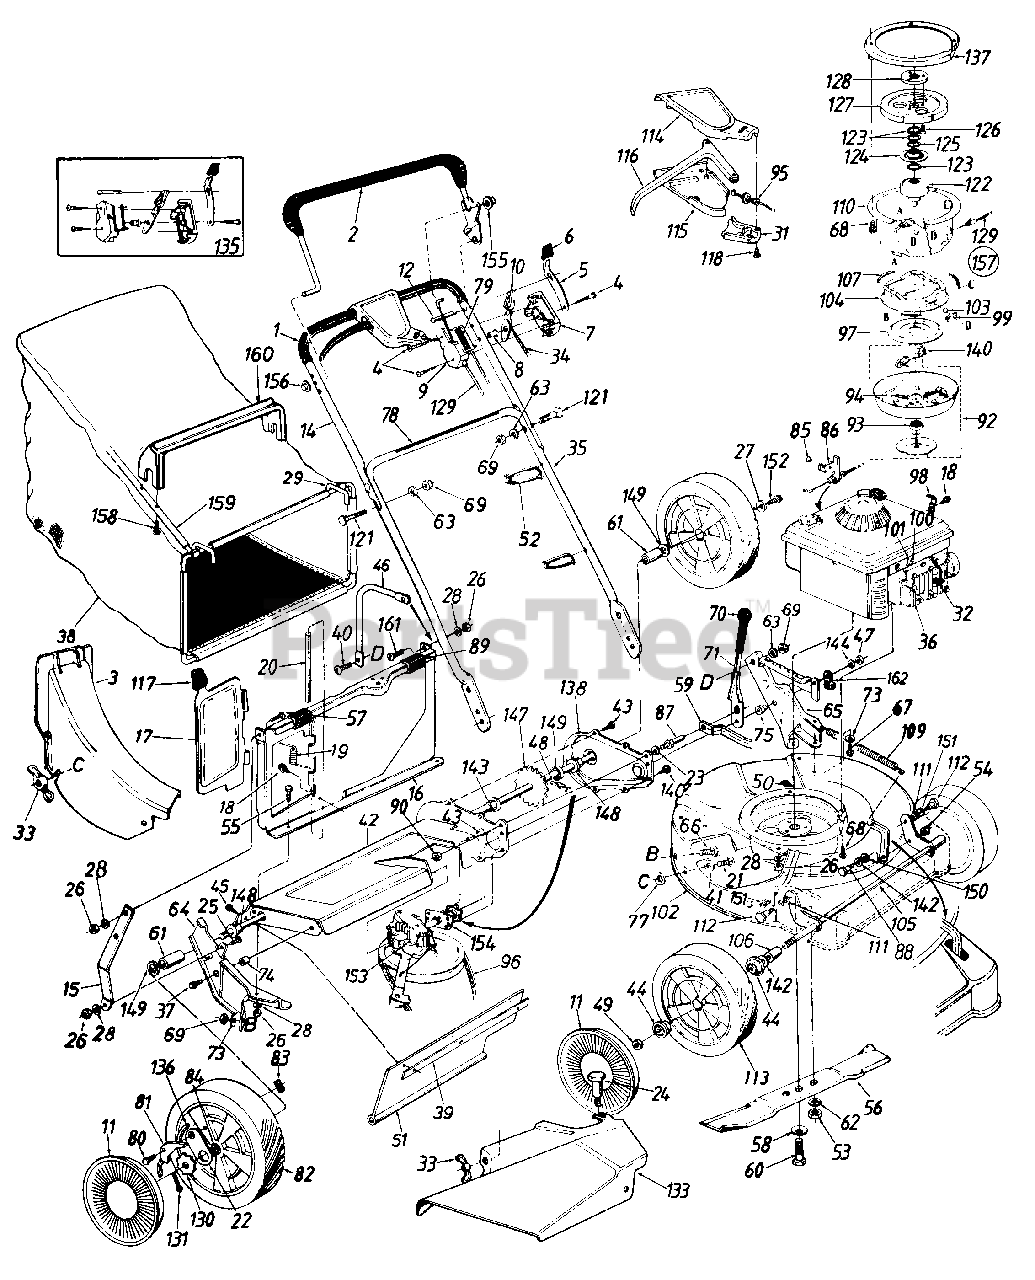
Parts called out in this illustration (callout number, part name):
1	Grip
2	Control Handle Ass'y.-L.H.
3	Rear Discharge Chute Ass'y.
4	Truss Mach. Scr. #12 x 1.50" Lg.
5	Lockout Spring
6	Spring Lever Knob
7	Control Panel Half
8	Control Disc Pin
9	Clutch Panel Half
10	Throttle Control Lever
11	Hub Cap (Radial)
12	Lock Pin .314" Dia. x 1.75"
14	Upper Handle
18	Hex B-Tap Scr. #10 x .38"
19	Torsion Spring
20	Pivot Pin
21	Carriage Bolt 1/4-20 x .62"
22	Pawl Plate
23	L-Wash. 3/8" I.D.*
24	Shoulder Bolt .312" Dia. x .18" Lg. Special
25	Hex Bolt 1/4-20 x .62" Lg.
26	Hex Nut 1/4-20 Thd.
27	Bell-Wash. 1/4" I.D.
28	L-Wash. 1/4" I.D.
31	S.P. Control Cover
32	Spark Plug Insulator
33	Wing Nut
34	Throttle Control Wire 58" Lg.
35	Lower Handle
36	Engine
37	Hex L-Wash. TT-Tap Scr. 3/8-16 x 1" Lg.
38	Grass Bag-Grey
39	Retaining Strip
40	Truss Mach. Scr. 5/16-18 x .75" Lg.
41	Fl-Wash. .344" I.D. x .62"
44	Flange Ball Bearing 1/2" I.D.
45	Hex AB-Tap Scr. 1/4 x .62"
46	Catcher Panel Support Arm
47	Hex Patch L-Nut 3/8-24 Thd.
48	#48 Chain .500" Pitch x 30 Links
49	Hex L-Nut 1/2-20 Thd.
51	Rear Flap 3.75" x 17.30" Lg.
52	Cable Tie
53	Hex Nut 3/8-24 Thd. (Grade 8)
54	Hex Jam Nut 3/8-16 Thd.
55	Hex Bolt 1/4-20 x .5" Lg.
56	21" Blade
57	Truss Mach. Scr. 1/4-20 x .75" Lg.
58	Bell-Wash. .46" I.D. x .88" O.D.
59	Height Adj. Connecting Arm
60	Hex Bolt 7/16-20 x 2.0" Lg. (Grade 5)
61	Spacer .513" I.D. x .703" O.D. x .69" Lg.
62	L-Wash. 3/8" I.D.
63	L-Wash. 5/16" I.D.
64	R.H. Handle Wheel Brkt. Ass'y.
65	L.H. Handle Wheel Brkt. Ass'y.
66	Carriage Bolt 5/16-18 x .62"
67	Hex Wash. Hd. B-Tap Scr. 5/16-18 x .5" Lg.
68	Hex Wash. Hd. TT-Tap Scr. 3/8-16 x 1.5" Lg.
69	Hex Nut 5/16-18 Thd.
71	Height Adj. Lever
73	Bell-Wash. 5/16" I.D.
74	Spacer .383" I.D. x .503" O.D.
75	Shld. Spacer .500" Dia. x . 1 00"
77	Bolt Retainer 1/4 x .50" O.D.
78	Instruction Label
79	Control Label
80	Shld. Scr. .342" Dia. x .268"
81	Pawl
82	Wheel Ass'y. Comp.-Rear 8 x 2.0"
83	Flat Weld Nut 1/4-20 Thd.
84	Sleeve Bearing 1/2" I.D.
85	Pop Rivet .156" Dia. x .379"
86	Cable Bracket
87	Shld. Pin 3/8-24 x 1.43" Lg.
88	Shoulder Bolt .5" Dia. x .295"
89	Panel Clip
90	Hex Jam Nut 3/8-24 Thd.
92	Clutch Blade Housing Ass'y.
93	Ball Brg. .669" I.D. x 1.574"
94	Comp. Spring .35" O.D. x 2.0" Lg.
95	S.P. Cable 48" Lg.
96	"V"-Belt
97	Clutch Cone
98	Casing Clamp
99	Ball Block
100	Hex B-Tap Scr. #10 x .62"
101	Casing Clamp
102	629/N 21" Deck Ass'y.
103	Steel Ball .50" Dia.
104	Brake Cup Cone
105	Front Axle Ass'y.
106	Sleeve .526" I.D. x .690" O.D. x .880" Lg.
107	Ext. Spring 1.75" Lg.
109	Extension Spring .75" O.D. x 8" Lg.
110	Clutch Housing
111	Intern. L-Wash. 3/8 I.D.
112	Shld. Bolt .623" Dia. x .425
113	Front-Wheel Ass'y. Comp. 8 x 2.0"
114	Self-Propelled Control Cover
115	Self-Propelled Control Cover
116	Control Lever
117	Door Grip
118	Fl-"C"-Sunk Hd. Tap Scr. #10 x .75" Lg.
121	Curved Carr. Bolt 5/16-18 x 1.38" Lg.
122	Fixed Pulley Adapter
123	Serrated Washer 1.0" I.D.
124	Serrated Pulley Half
125	Wave Washer 1.005" I.D.
126	Flat HD Tap Scr. 1/4-20 x .625" Lg .
127	Flywheel
128	Flywheel Adapter
129	Control Cable-49" Lg.
130	Ratchet Wheel 1.62" O.D.
131	Cotter Pin 1/8" Dia. x 1.00" Lg.
133	Side Chute Deflector Ass'y.
135	Kit-Control Housing Comp.
136	Spring-Nylon
137	Engine Mounting Plate Cover
142	Fl-Wash. .510 I.D. x.75" O.D.
143	Hex Flange Brg. .506" I.D.
144	Fl-Wash. .385" I.D. x.87" O.D.
147	Rear Shaft Ass'y. 21.94" Lg.
148	Hex Flange Bearing .506" I.D. Plastic
149	Fl-Wash. .531" I.D. x .930" O.D.
150	Bell-Wash. .515" I.D. x 1.0" O.D.
151	Flanged Nyliner Brg.
152	Hex Bolt 1/4-20 x .62" Lg. (Grade 5)
153	Transmission Comp.
154	Hex Bearing Cup
155	Push Cap
156	Push Cap
157	Blade Brake Clutch Ass'y. Comp.
158	Hex AB-Tap Scr. 1.25" Lg.
160	Bag Handle
161	Truss Mach. Scr. 1/4-20 x .62"
162	Clamp
